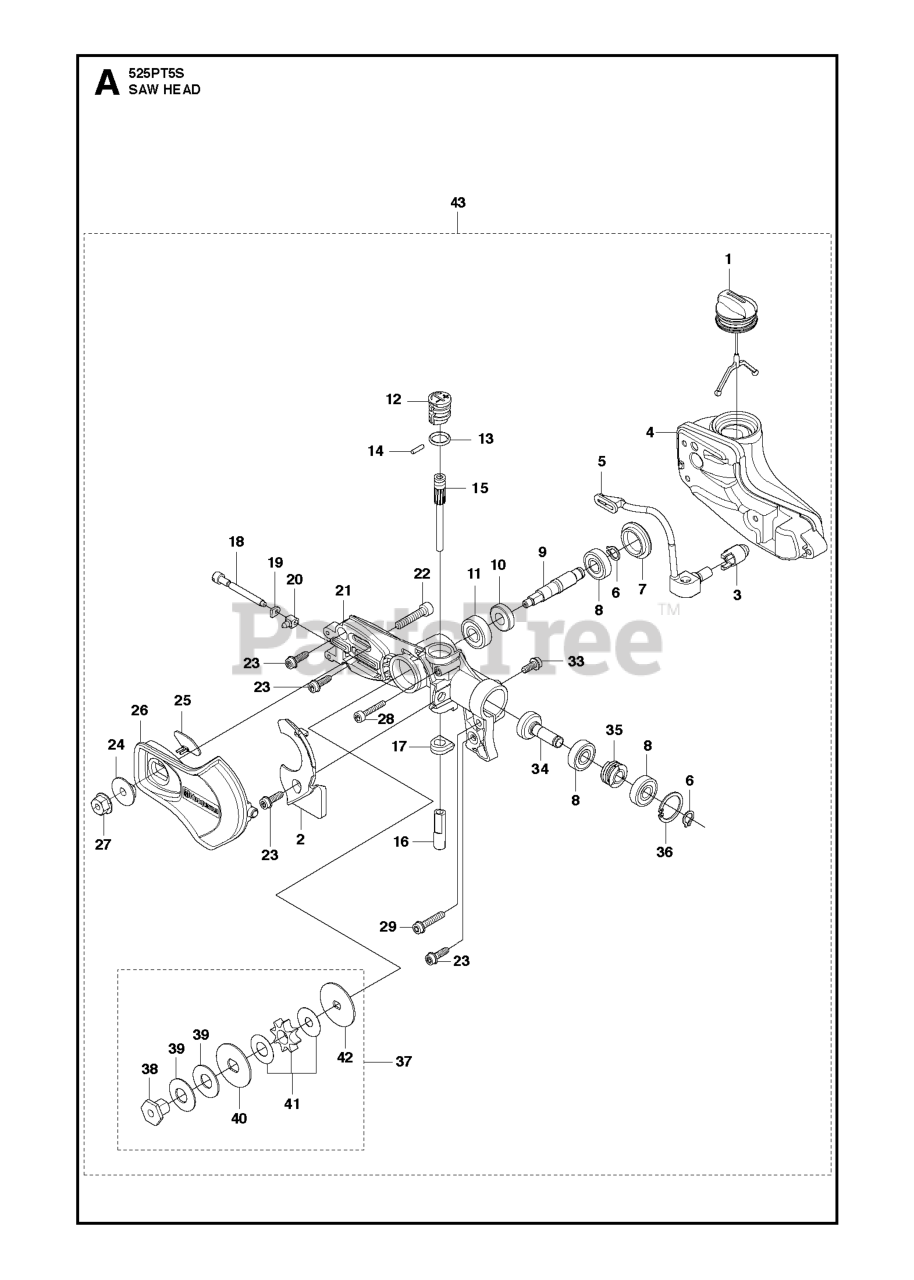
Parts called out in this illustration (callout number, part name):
1	TANK CAP ASSY
3	OIL SCREEN
6	RETAINING RING
8	BALL BEARING
10	GEAR WHEEL
11	BALL BEARING
14	NEEDLE ROLLER
15	PISTON PUMP
16	PUMP CYLINDER
21	GEAR HOUSING
22	SCREW IHSCM
27	HEXAGON NUT FLANGED
28	SCREW ITXSCM
33	SCREW
36	RETAINING RING
37	SPROCKET KIT 1/4"
37	SPROCKET KIT 3/8"
39	DISC SPRING
41	SPROCKET KIT 1/4"
41	SPROCKET KIT 3/8"
42	WASHER
43	POLE SAW HEAD
43	POLE SAW HEAD TORQUE LIMITER
